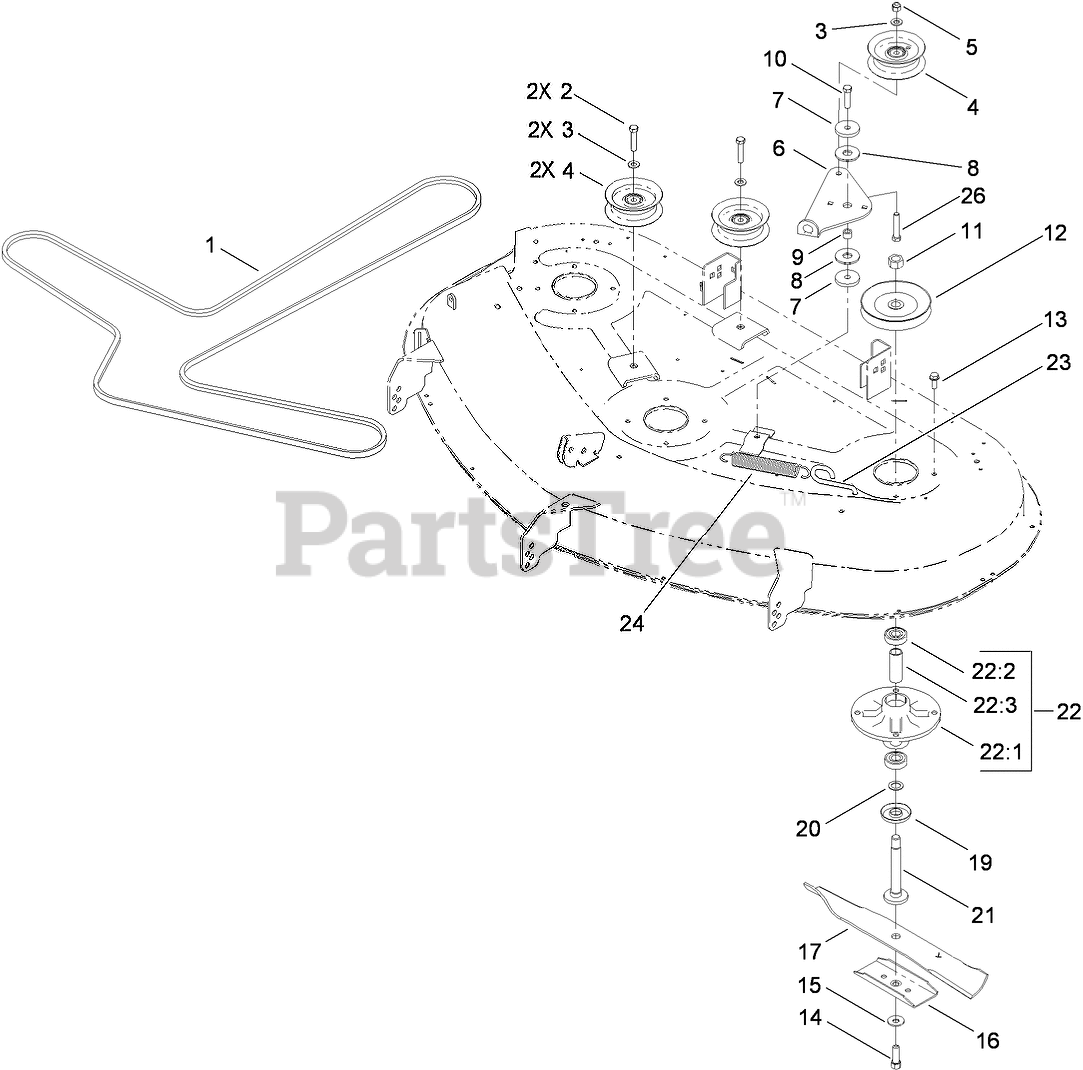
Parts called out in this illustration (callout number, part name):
1	V-BELT
2	SCREW-HH
3	WASHER-FLAT
4	PULLEY-IDLER, FLAT
5	NUT-LOCK, NI
6	ARM-IDLER
7	WASHER-PLAIN
8	WASHER-FRICTION, COMPOSITE
9	SPACER
10	SCREW-HH
11	NUT-HEX
12	PULLEY
13	SCREW-TAPTITE
14	SCREW-HH
15	WASHER-BELLEVILLE
16	STIFFENER-BLADE
17	BLADE-17.5 INCH, HIGH LIFT
19	SHIELD-BEARING
20	SPACER
21	SHAFT-SPINDLE
22	SPINDLE ASM
22:1	HOUSING-SPINDLE
22:2	BEARING-BALL
22:3	SPACER
23	HOOK-RETURN, SPRING
24	SPRING-EXTENSION
26	SCREW-HH
